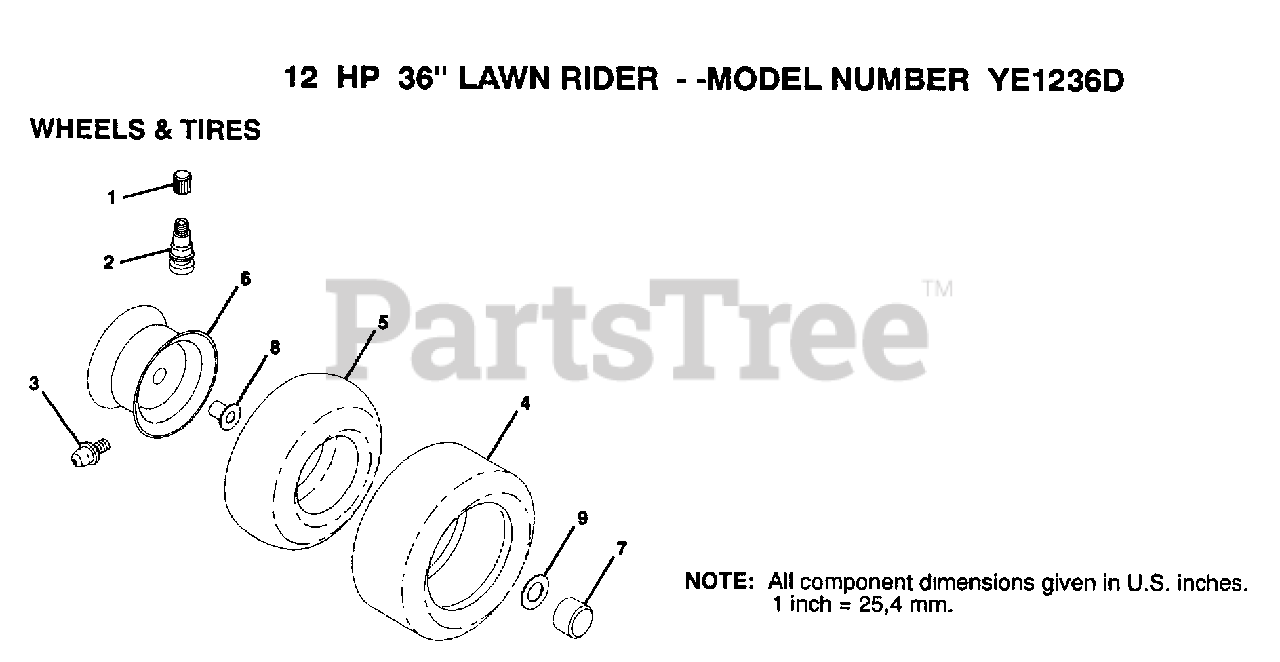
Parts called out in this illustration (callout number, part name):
1	VALVE CAP
2	VALVE STEM LT
3	FITTING LT
5	TUBE.5.3/4.5/6
7	HUB CAP
8	"FLANGE, BEARING"
9	WASHER
